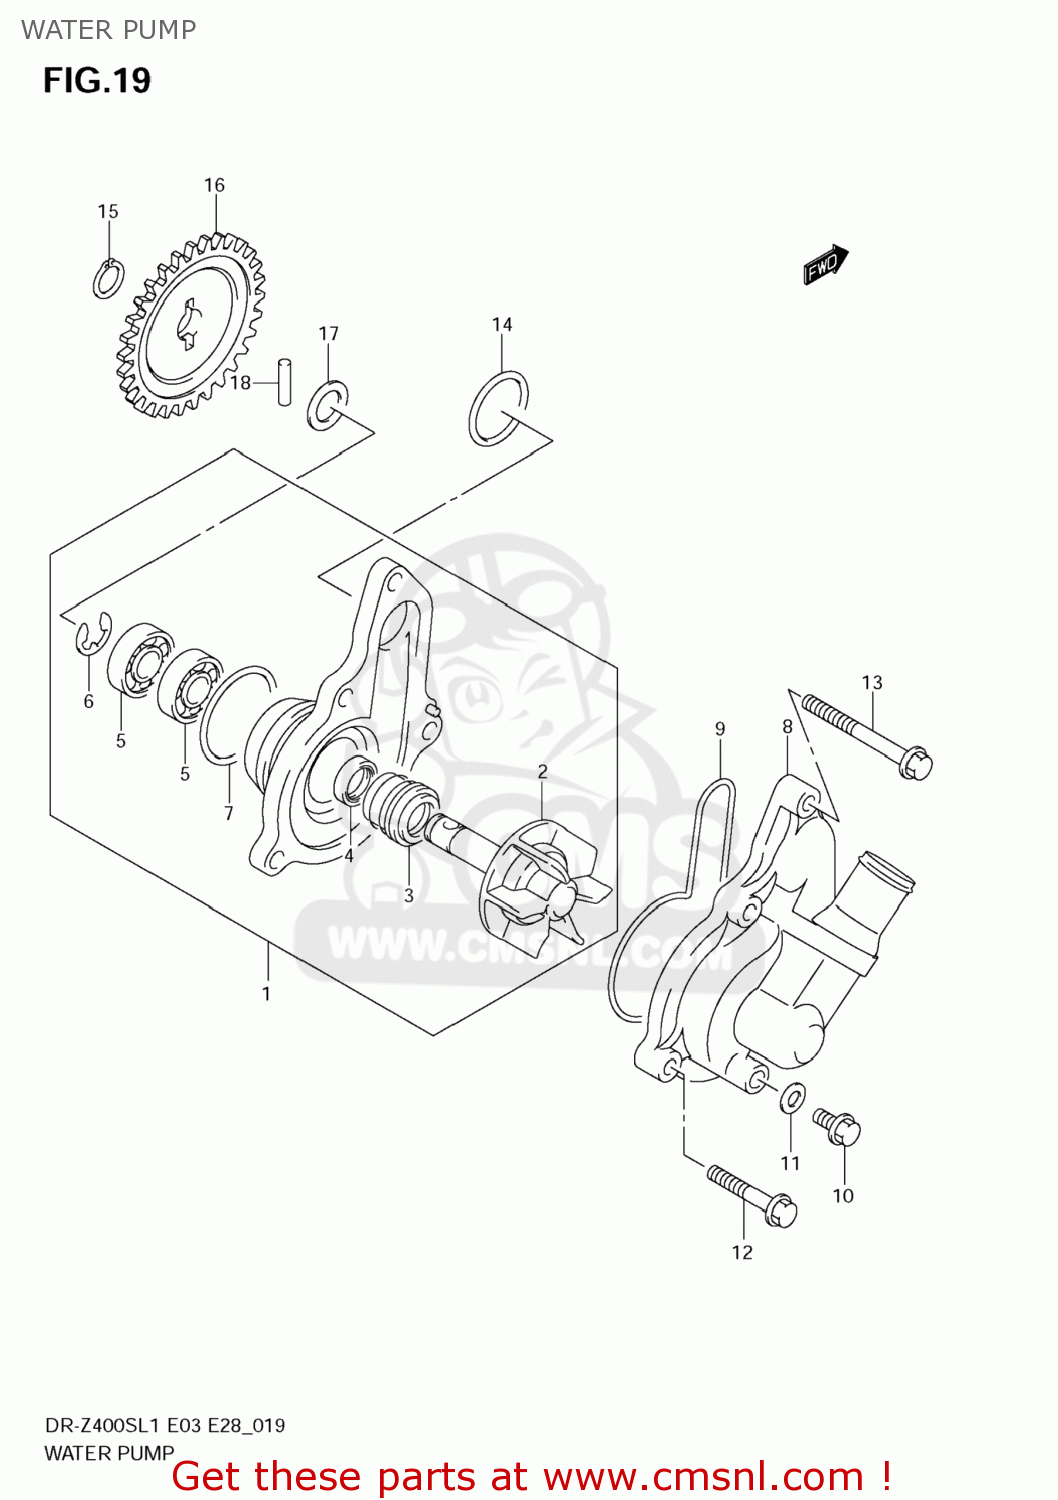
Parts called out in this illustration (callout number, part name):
1	PUMP ASSY,WATER
2	IMPELLER SHAFT
3	SEAL,MECHANICAL
4	SEAL,OIL(10X21X5)
5	BEARING
6	E RING
7	O RING,WATER PUMP HOLDER
8	CASE,WATER PUMP
9	O RING,WATER PUMP CASE
10	BOLT
11	GASKET(6.4X11.5X0.8) (NAS)
12	BOLT(6X30)
13	BOLT(6X45)
14	O RING(D:2.4,ID:21.8)
15	CIRCLIP
16	GEAR,WATER PUMP DRIVEN
17	SHIM(10X18X0.5)
18	PIN(4X18.5)
